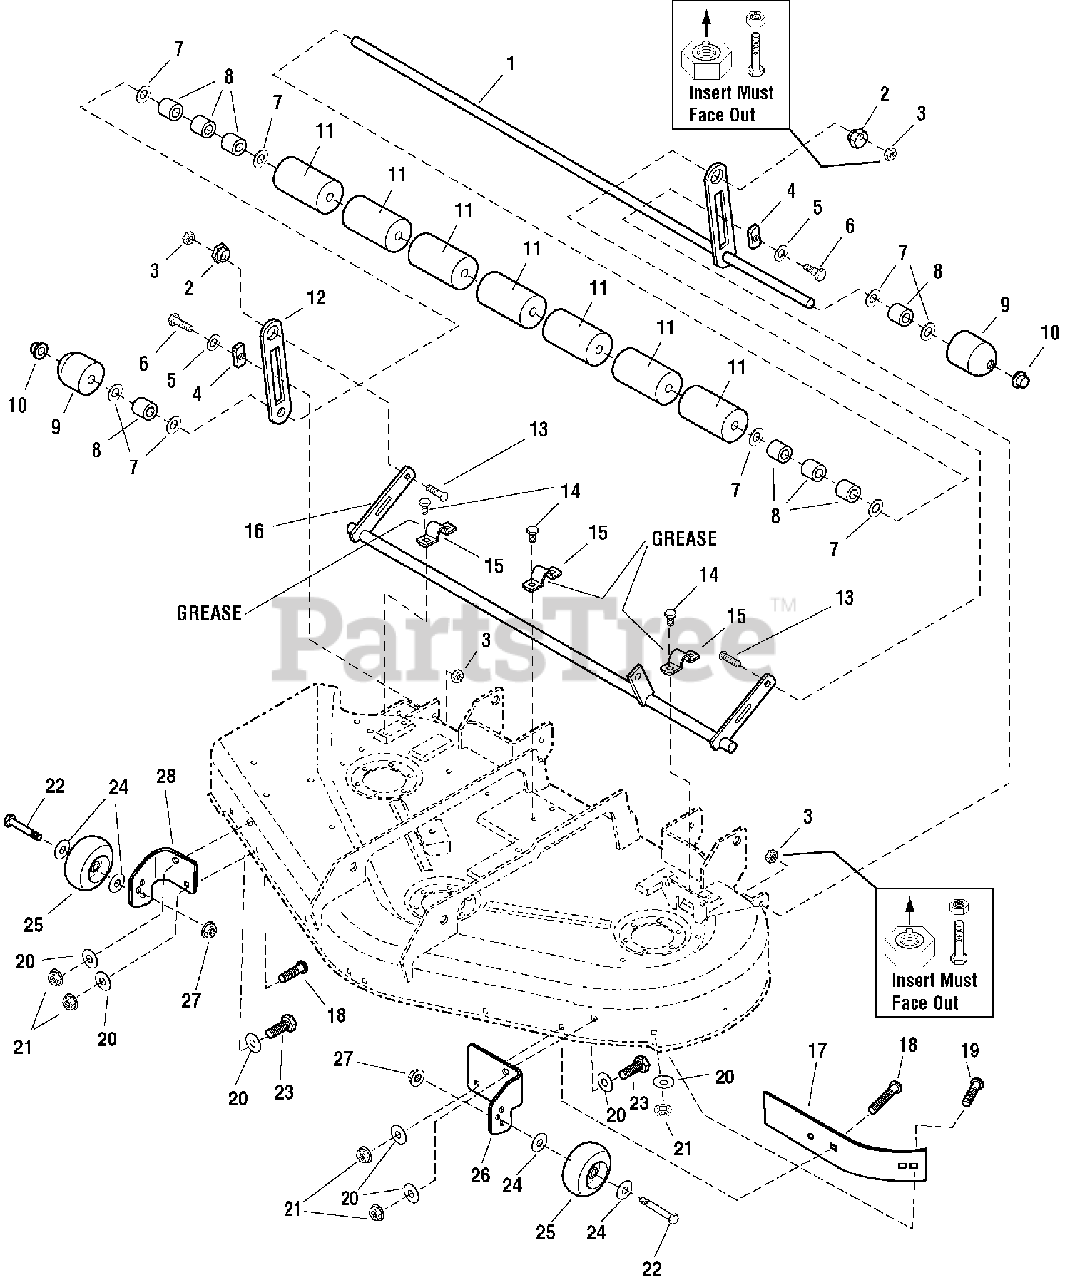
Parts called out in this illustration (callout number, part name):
1	SHAFT, ROLLER, 44"
2	NUT, ADJUSTER
3	NUT, HEX ALUMINUM INSERT LOCK, 3/8-16
4	SLIDE
5	WASHER, PLAIN, 1/2
6	BOLT, SHOULDER, 3/8-16
7	WASHER, .661 ID X 1.12 OD X .11, BLACK
8	SPACER, 25/64 X 13/16 X 13/16, STEEL, BLACK
9	ROLLER, ROUNDED
10	NUT, PUSH
11	ROLLER
12	BAR, ROLLER
13	CARRIAGE BOLT, 3/8-16 X 1-1/2
14	CAPSCREW, HEX HEAD TAPTITE, 5/16-18 X 3/4
15	STRAP
16	SHAFT, DECK LIFT, 44"
17	SHORT BLOWOUT BAFFLE
18	CARRIAGE BOLT, 5/16-18 X 1
19	CARRIAGE BOLT, 5/16-18 X 3/4
20	WASHER, 5/16, PLAIN, SAE
21	NUT, 5/16-18, HEX, NYLON LOCK
22	BOLT, REAR WHEEL
23	CAPSCREW, HEX HEAD,5/16-18 X 1
24	WASHER
25	GAUGE WHEEL
26	BRACKET, GAUGE WHEEL, LH
27	NUT, FLANGE, SIDELOCK, 3/8-16
28	BRACKET, GAUGE WHEEL, RH
